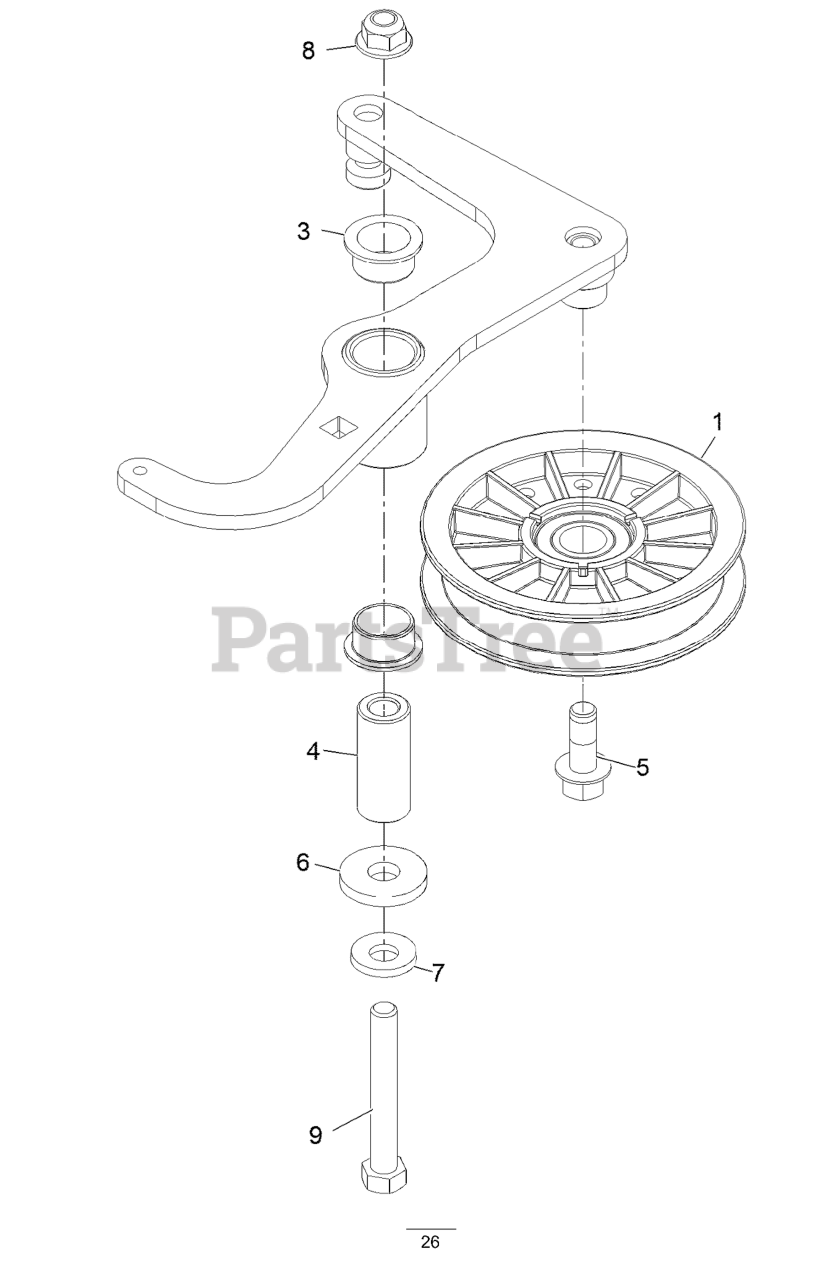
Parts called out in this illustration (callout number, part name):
1	PULLEY-IDLER, FLAT
3	BUSHING-FLANGE
4	SPACER, PIVOT
5	SCREW-HFH
7	WASHER-BELLEVILLE
8	NUT-HF, NI
9	SCREW-TAP
